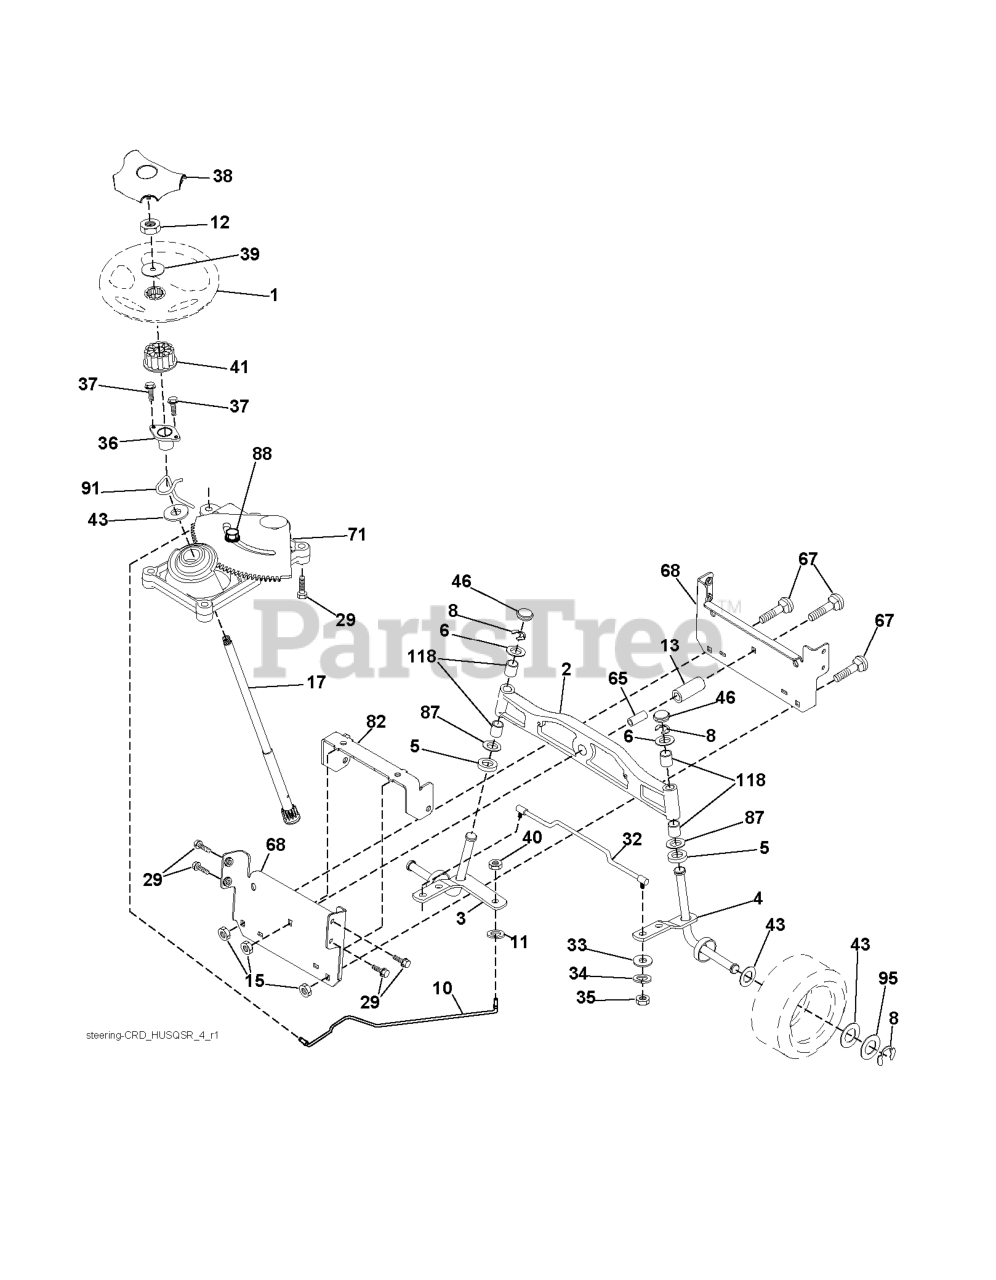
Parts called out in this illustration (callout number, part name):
1	RP WHEEL.STEER.HUSQ.PREM.OVMLD
2	AXLE ASSY FRONT
3	SPINDLE.ASM.LH.15"TIRES
4	SPINDLE.ASM.RH.15"TIRES
5	THRUST WASHER
10	DRAGLINK.15".TIRES.2001
11	WASHER, LOCK 3/8
13	TUBE, PIVOT AXLE
15	NUT
17	SHAFT STEERING SPLINE
29	SCREW, 3/8-16X3/4
33	WASHER M
34	WASHER.LOCK.HVY.HLCL.SPR.5/16
35	NUT, CROWNLOCK
36	BUSHING, STEERING
37	SCREW.TT.#10-32X.5.3/8.FLANGE
38	RP INSERT.CAP.WHL.STRG.HUSQ.
39	WASHER.11/32
40	NUT CROWNLOCK 3/8-24
41	ADAPTER, WHEEL STNG..
42	BOOT, STEERING
44	SHAFT.EXTEN.STRG.SPLINE
46	CAP.SPINDLE.BLACK
65	SPACER BRACE AXLE
67	BOLT CARRIAGE
68	BRACE.AXLE.15"TIRES
71	STEERING ASM
82	BRACKET.SUSP.CHASSIS.FRONT.15
87	WASHER, FLAT .781 X 1 1/2"
88	BOLT, SHOULDER 7/16-20
91	CLIP.STEERING
95	WASHER.HARDENED
118	BUSHING, AXLE CAST
